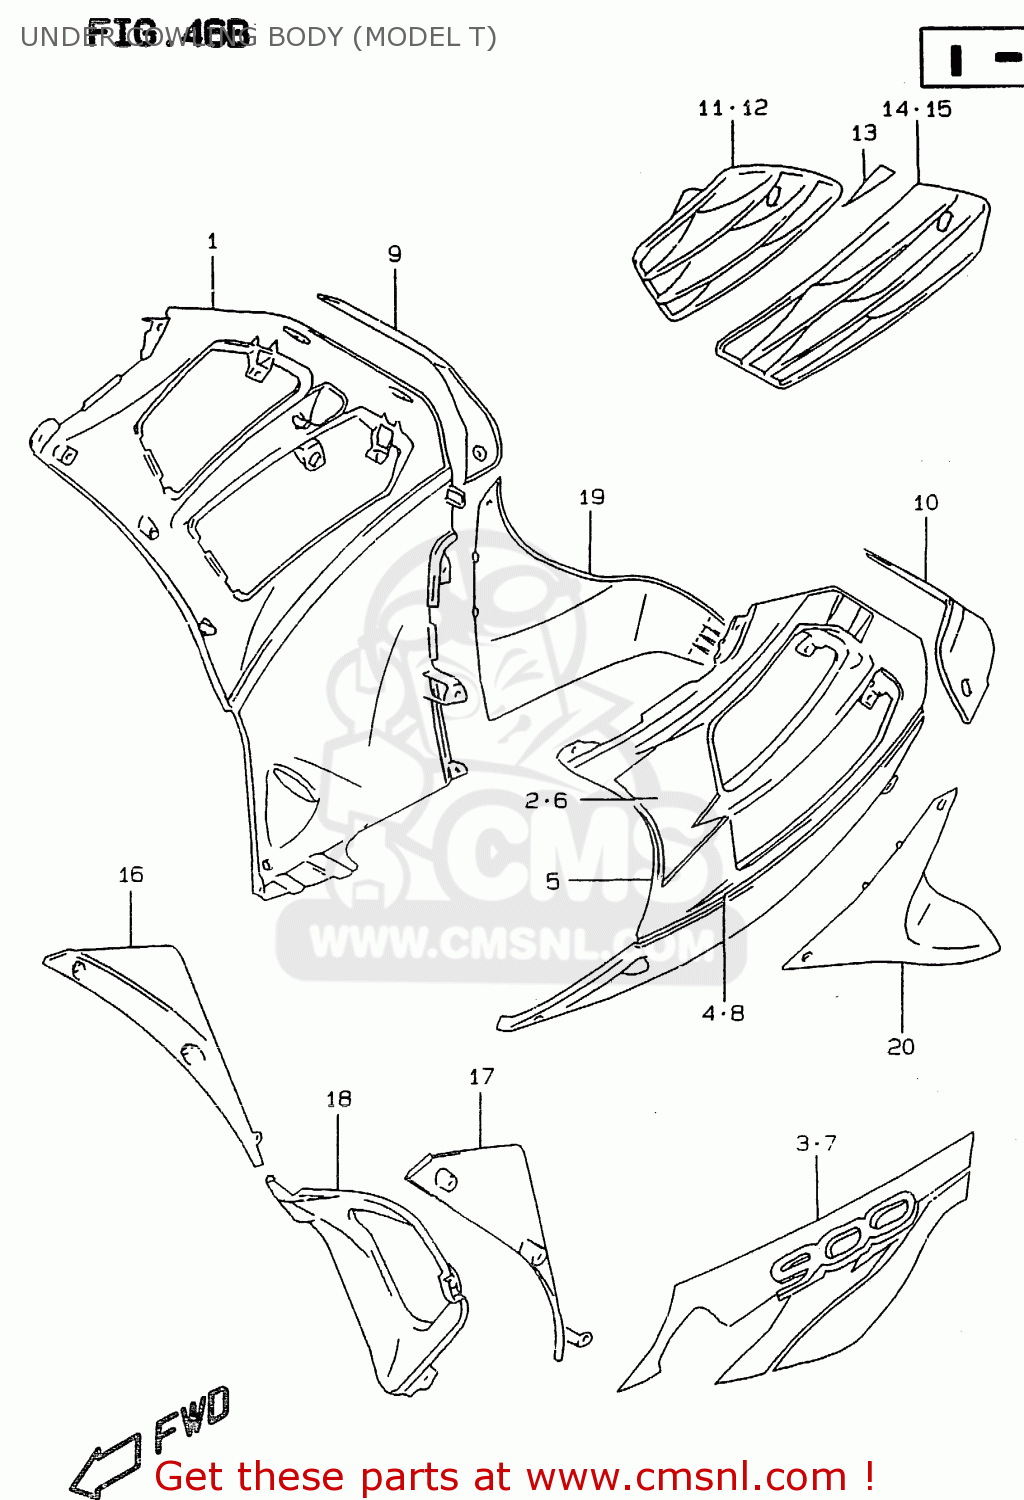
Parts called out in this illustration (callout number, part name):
1	COWLING ASSY,UNDER,R(PURPLE)
2	TAPE SET,UNDER UPR,R
3	TAPE,UNDER,LOWER,RIGHT
4	TAPE,UNDER COWL,R
5	COWLING ASSY,UNDER,L(PURPLE)
6	TAPE SET,UNDER UPR,L
7	TAPE,UNDER LWR,L
8	TAPE,UNDER COWL,L
9	PANEL,UNDER,R
10	PANEL,UNDER,L
11	COVER,UNDER UPR,R
12	COVER,UNDER UPR,L
13	TAPE,UNDER COVER,L
14	COVER,UNDER COWL LWR,R
15	COVER,UNDER COWL LWR,L
16	COWLING,UNDER INNER,R
17	COWLING,UNDER INNER,L
18	COWLING,UNDER CTR
19	COWLING,UNDER RR,R
20	COWLING,UNDER RR,L
